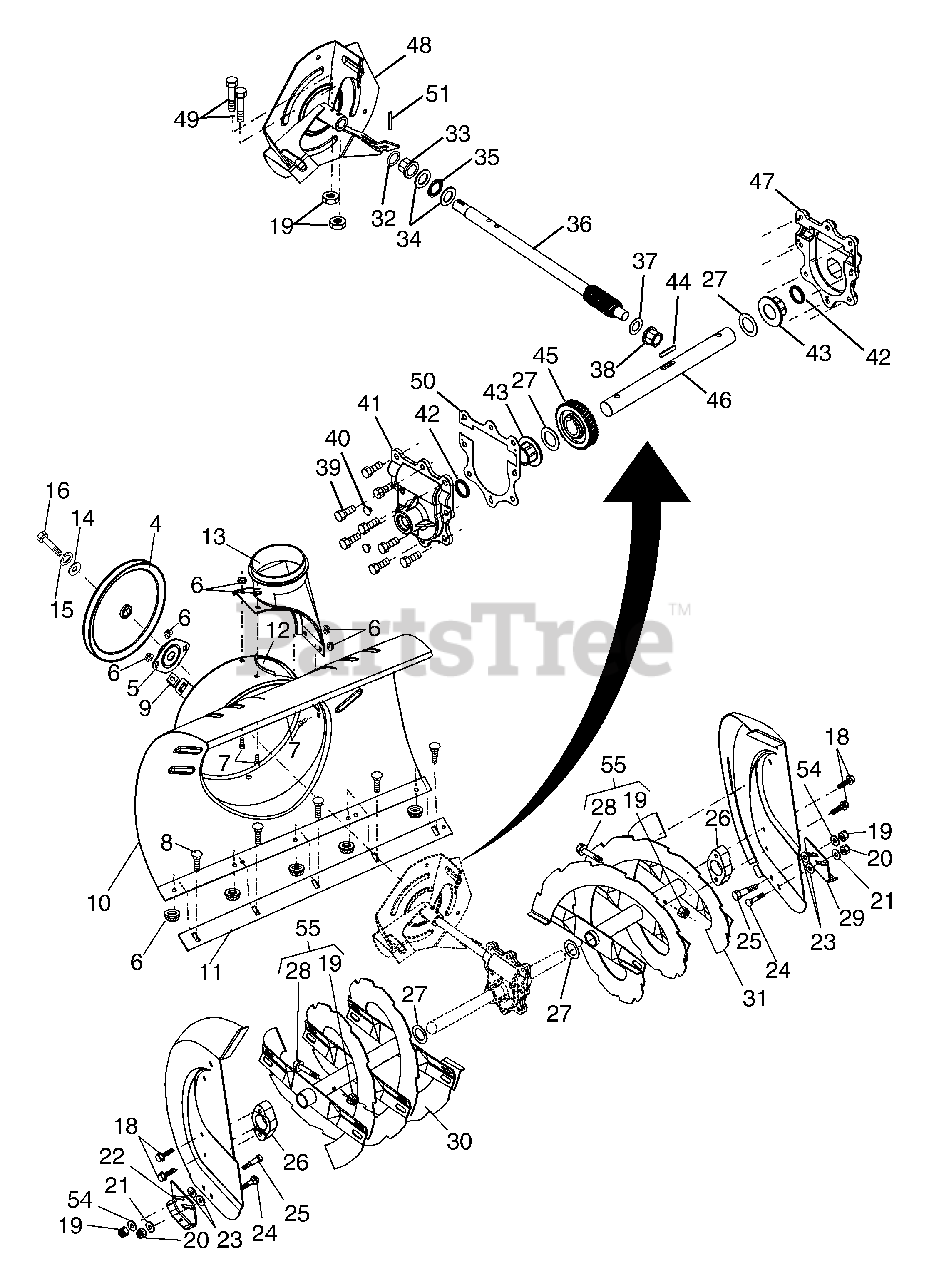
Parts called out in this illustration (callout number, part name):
4	Pulley, Impeller
5	Bearing Assembly, Flange
6	Nut, Hex Flange 5/16-18
7	Bolt, Flat Head, Carriage 5/16-18 x 5/8
8	Bolt, Carriage 5/16-18 x 5/8
9	Nut, Cage 3/8-16
10	Housing, Auger
11	Bar, Scraper
12	Bracket, Corner Discharge
13	Base, Discharge Chute
14	Washer, Flat
15	Washer, Lock 5/16
16	Screw, Hex Head 5/16-18 x 3/4
18	Screw, Hex Head 5/16 x 1
19	Nut, Hex Lock 1/4-20
20	Nut, Hex Lock 5/16-18
21	Washer, Flat 5/16
22	Skid Plate, RH
23	Washer, Nylon, Friction
24	Bolt, Carriage 5/16-18 x 3/4
25	Bolt, Shoulder 1/4-20
26	Bearing, Auger
27	Washer, Thrust, 1"
28	Bolt, Shear
29	Skid Plate, LH
30	Auger Assembly, RH
31	Auger Assembly, LH
32	O-Ring
33	Bushing, Flange 3/4
34	Washer, Thrust 3/4
35	Bearing, Thrust 3/4
36	Shaft, Impeller
37	Washer, Thrust 5/8
38	Bushing, Flange 5/8
39	Screw, Hex Head 5/16-18 x 3/4
40	Plug, Case
41	Housing, Gearbox, RH
43	Bushing, Flange, 1"
44	Key, Square 1/4 x 1/4 x 7/8
45	Gear, Worm
46	Shaft, Auger
47	Housing, Gearbox, LH
48	Impeller Assembly
49	Screw, Hex Head 1/4-20 x 1-5/8
50	Gasket, Gearbox
51	Pin, Roll 3/16 x 1-1/8
54	Washer, Flat 1/4
55	Kit, Shear
